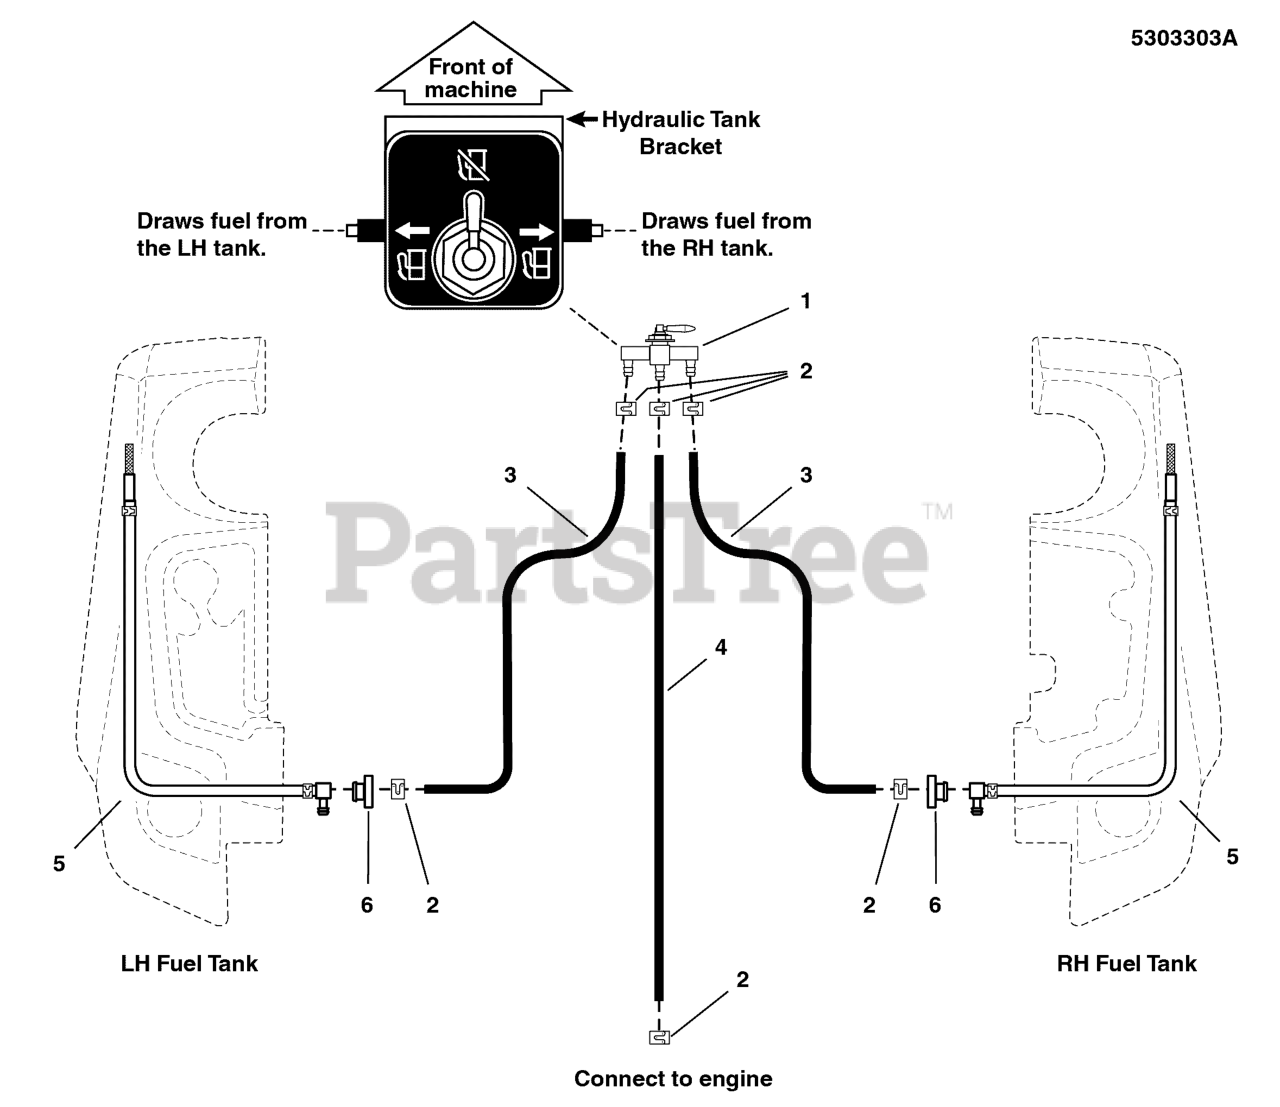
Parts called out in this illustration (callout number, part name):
1	VALVE, FUEL, STR. OUTLET
2	CLAMP, HOSE, EXTERNAL, 1/2 - RED
3	HOSE, 1/4" FUEL, 27.00"
4	HOSE, 1/4 FUEL, 8.00"
5	PICKUP TUBE ASM, FUEL TANK, 23" (SV)
6	BUSHING-FUEL TANK RED RUBBER
